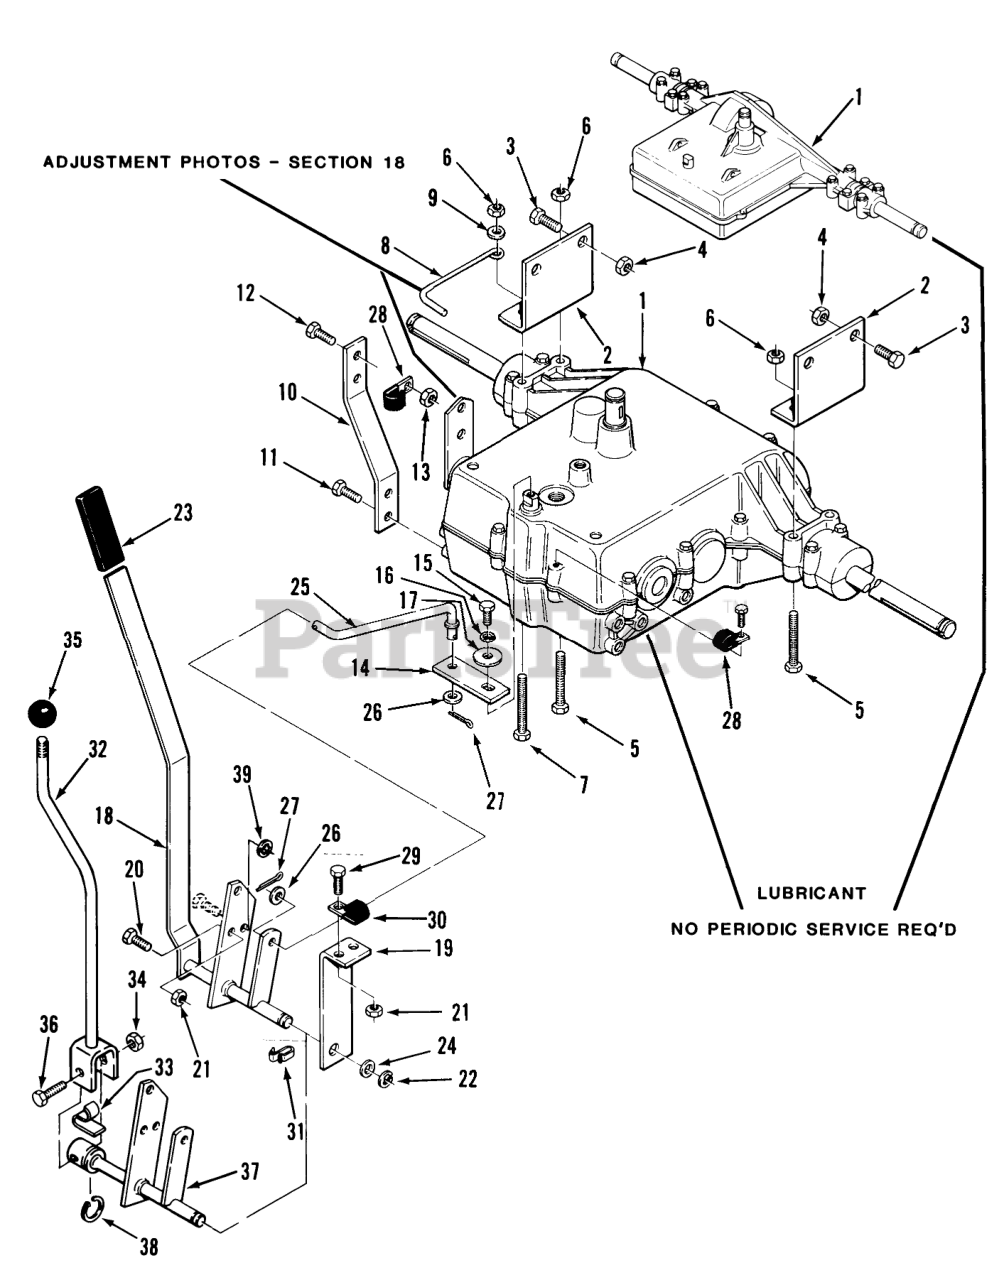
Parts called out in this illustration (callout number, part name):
1	Peerless Transmission (900-028) 108-4 Only
2	Bracket-Rear Axle
3	BOLR HWH 3/8-16X7/8
4	NUT
5	HHCS
6	Nut
7	Pin-Cotter
8	STOP BRAKE
9	WASHER 5/16 SAE
10	STRAP TORQUE
11	Screw
12	Bolt
13	Nut
14	LEVER LOWER SHIFT
15	Bolt 1/4-28 X 7/8
16	Washer
17	WASHER
18	ASSY LEVER SHIFT R
19	SUPPORT SHIFT
20	Bolt
21	Nut
22	E Ring
24	Washer
25	DECAL SHIFT
26	WASHER 5/16 SAE
27	Cotter Pin
28	J-CLIP
29	BOLT 5/16-18 X 3/4
30	J-CLIP
31	CLIP-CABLE
32	Handle 112-C Only
33	CLIP-SPRING
34	LOCKNUT 5/16-18GR.B
35	KNOB
36	HHCS
37	Shift Lever 112-C Only
38	Snap Ring
39	Washer-Lock
